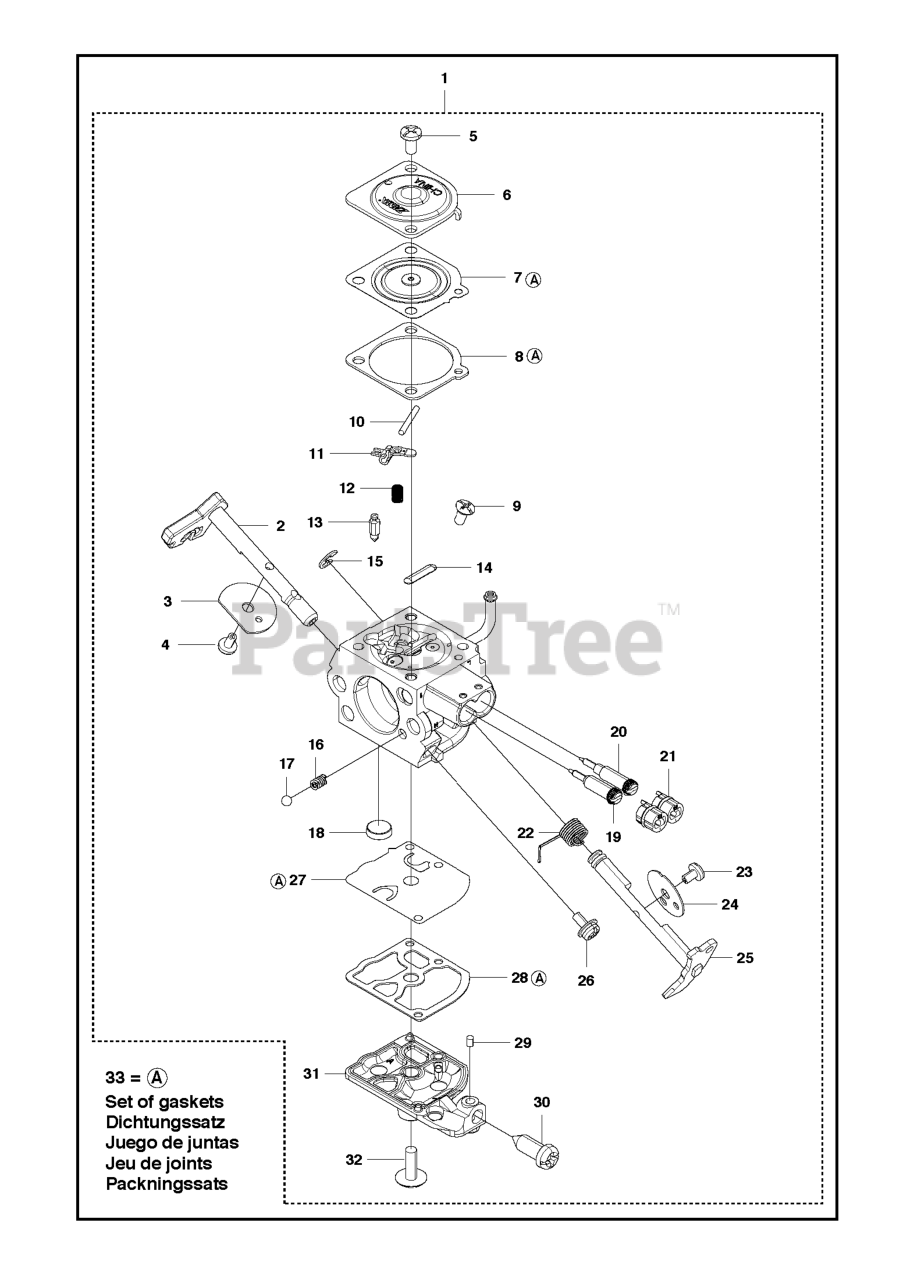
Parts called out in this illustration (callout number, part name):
1	CARBURETOR C1Q-EL52
8	GASKET METERING SIDE
10	PIN RETAINING SCREW
12	SPRING
13	INLET NEEDLE
19	SCREW
20	IDLE SCREW
21	LIMITER CAP KIT
22	SPRING THROTTLE
24	THROTTLE FLAP
27	PUMP DIAPHRAGM
33	GASKET SET
